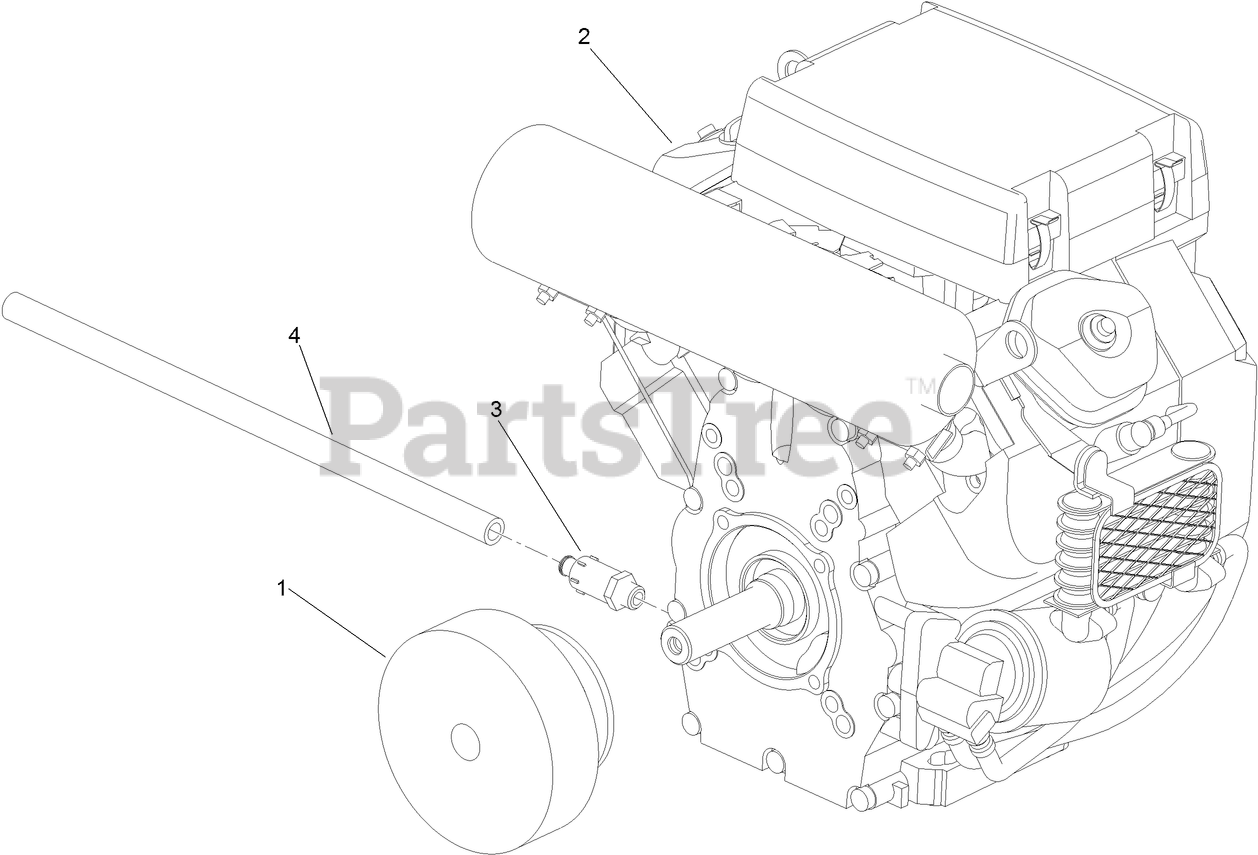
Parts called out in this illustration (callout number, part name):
1	CLUTCH-CHIPPER
2	ENGINE-KOHLER, CH730-3262
3	VALVE-DRAIN, OIL
